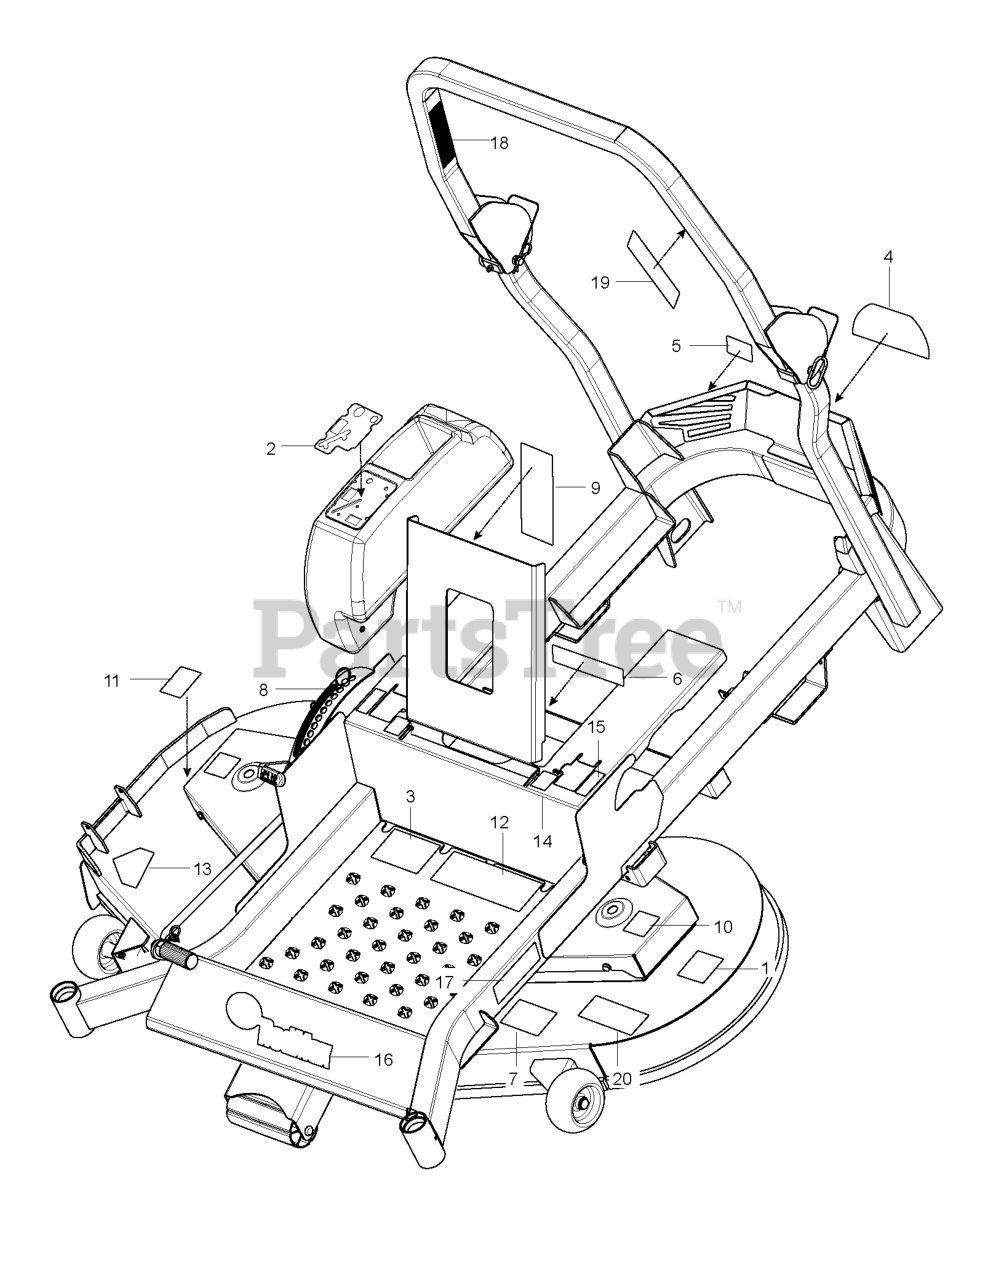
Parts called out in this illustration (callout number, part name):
1	DECAL DECK DECAL DECAL.DECK.52
2	DECAL CTRL PANEL GRAPHIC DECAL
3	DECAL ZTR STARTING DECAL
4	DECAL ZTR BRAND GRAPHIC DECAL.
5	DECAL, BELT DRIVE
6	EURO DECAL-BATTERY WARNIN6
7	DECAL, BELT ROUTING
8	DECAL ZTR INSTRUCTION GRAPHIC
9	DECAL, SERVICE
10	DECAL.DECK.6MIL.EURO.NOSTEP
11	DECAL.DECK.6MIL./DEF.SHLD.WARN
12	DECAL ZTR WARNING DECAL DECAL.
13	DECAL, DECK DEFLECTOR, WARNING
14	DECAL.ZTR.TRACKING.GRAPHIC
15	DECAL.ZTR.MTNCONTROL.2015.PPRO
16	DECAL ZTR BRAND GRAPHIC DECAL.
17	DECAL ZTR SIDE RAIL GRAPHIC DE
18	DECAL, ROPS, WARNING
19	DECAL ROPS
20	FOOT PAD
